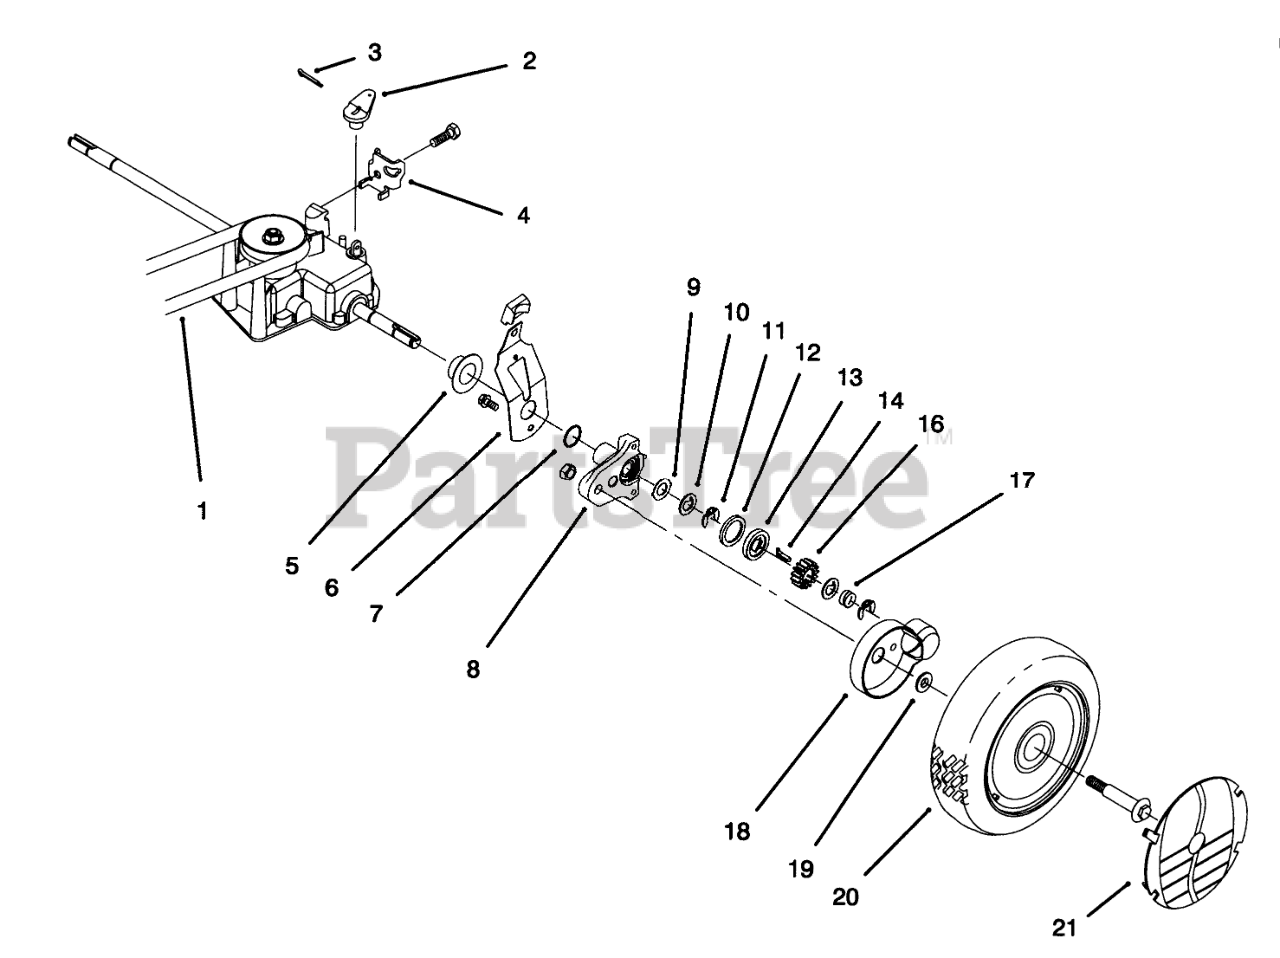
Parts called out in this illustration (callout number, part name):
1	V-BELT E
2	LEVER-SHIFT
3	PIN-COTTER
4	CLAMP-CABLE
5	CAP-END
6	SPRING ARM ASM
7	O-RING
8	PIVOT ARM ASM
9	WASHER-ARM, PIVOT
10	WASHER-THRUST, KEYED
11	RING-CLIP, LOCKING
12	RING-FRICTION
13	WASHER-CLUTCH
14	KEY-ROCKING, LH
16	GEAR-PINION
17	SPRING-COMPRESSION
18	COVER-WHEEL
19	SPACER-COVER, WHEEL
20	WHEEL AND TIRE ASM (W/GEAR)
21	WHEEL COVER
